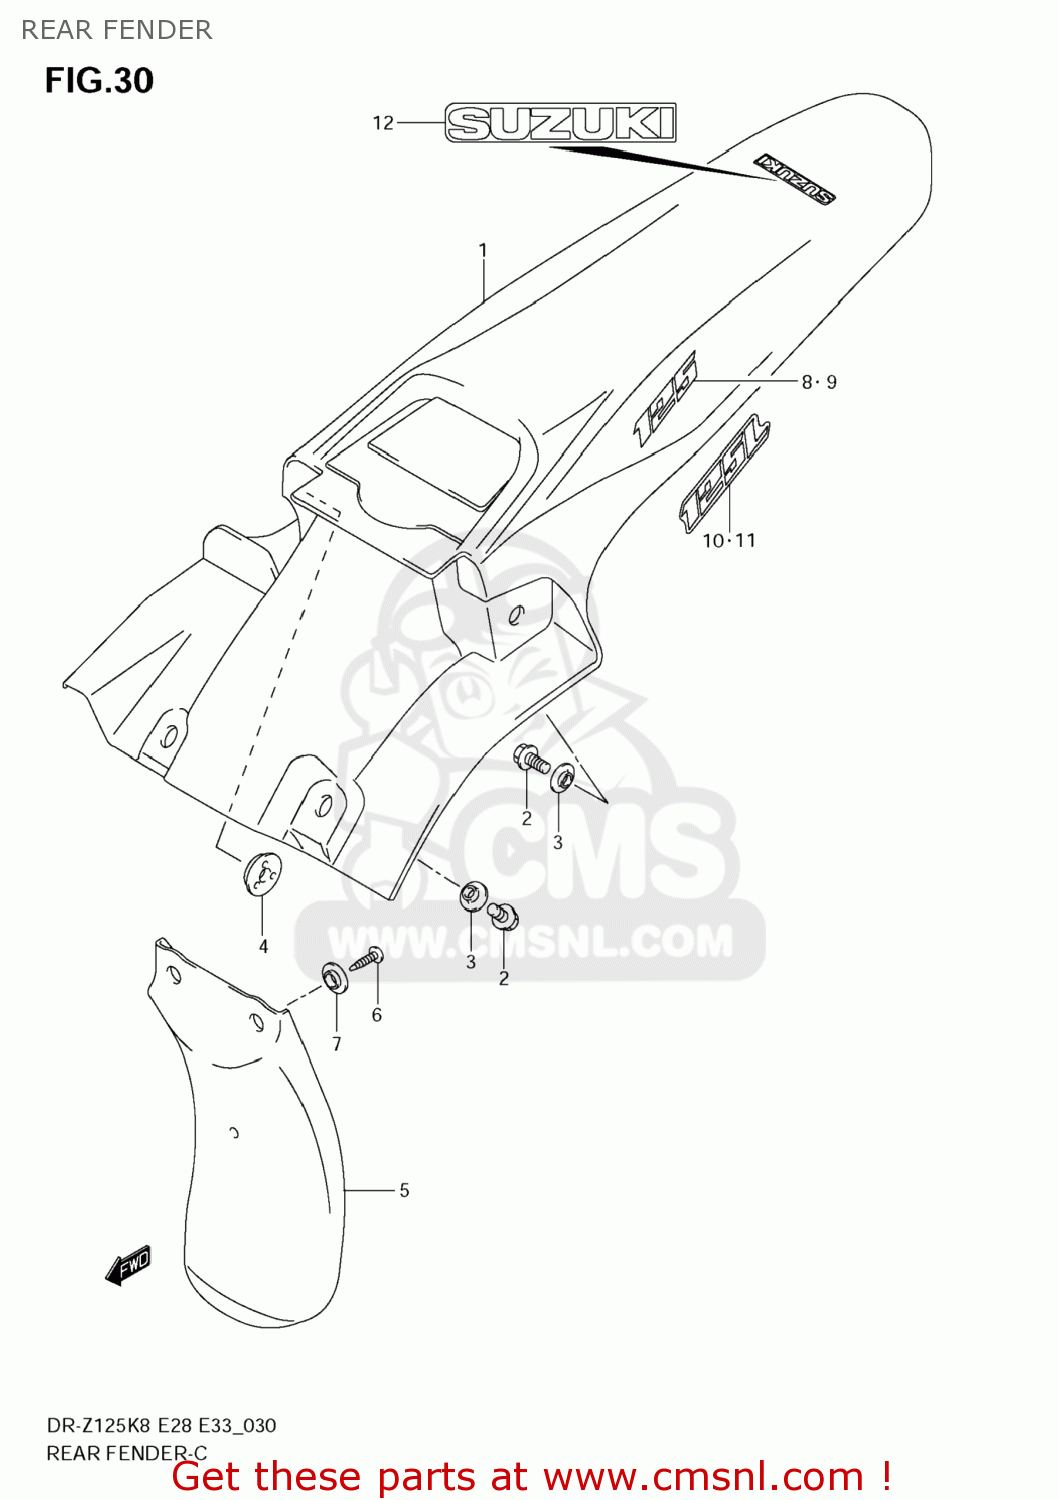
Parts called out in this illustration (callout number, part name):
1	FENDER,RR
2	BOLT(6X16)
3	WASHER
4	WASHER
5	MUDGUARD,RR FENDER FR
6	SCREW(5X16)
7	WASHER
8	EMBLEM,125,R
9	EMBLEM,125,L
10	EMBLEM,125L,R
11	EMBLEM,125L,L
12	EMBLEM,SUZUKI
